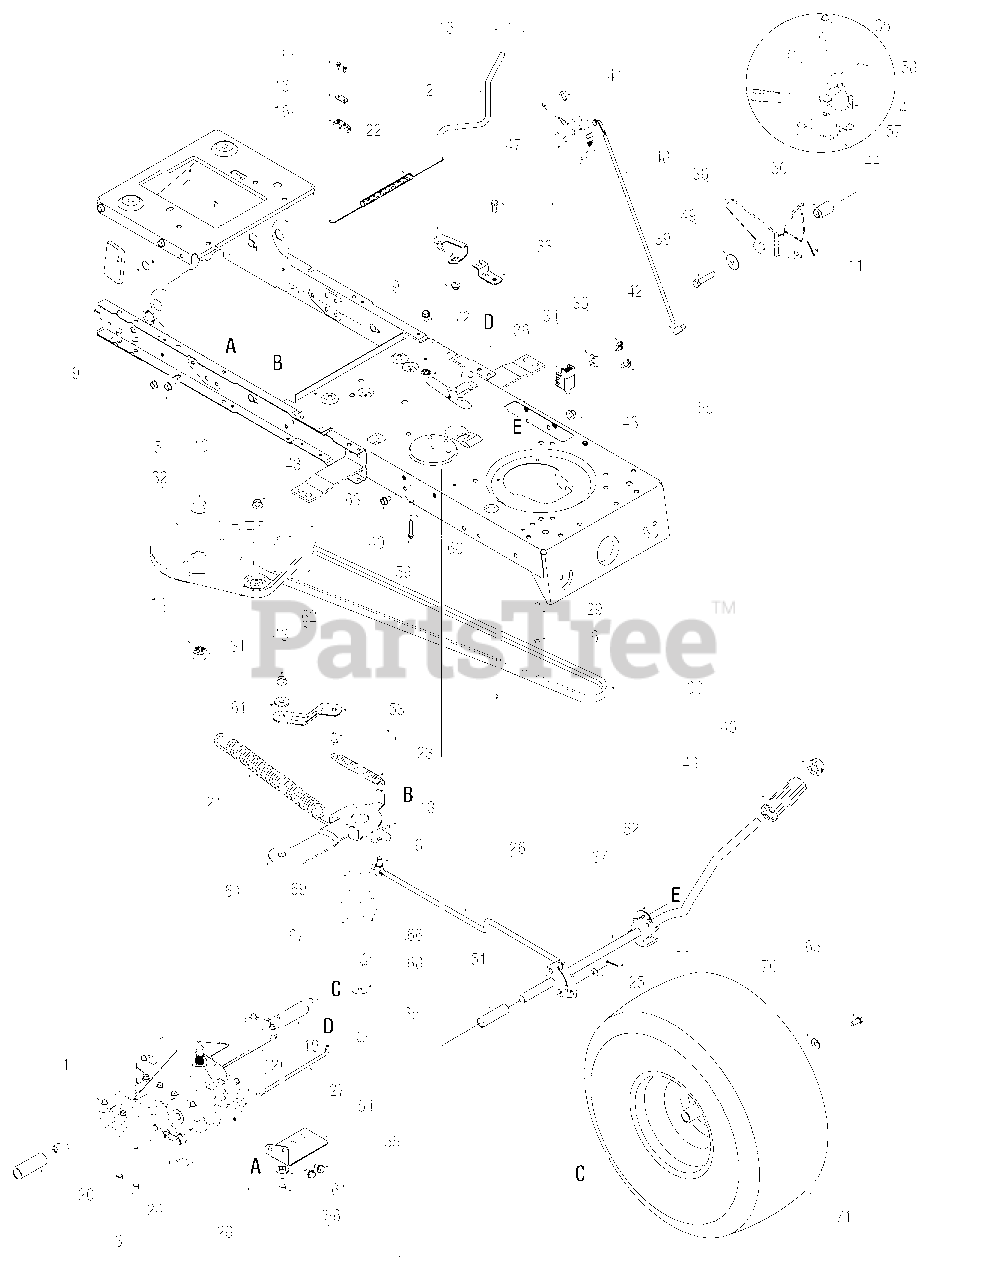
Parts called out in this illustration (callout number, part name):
1	Transmission Assembly
2	Lever Assembly, Shift
3	Screw, 5/16-18, 2.75, Gr5
4	Screw, #8-18, 0.500
5	Screw, 5/16-12, 0.750
6	Screw, 1/4-20, 1.250
7	Screw, 5/16-18, .75, Gr5
8	Ferrule, 3/8-24 x .375 Dia.
9	Nut, Flange Lock, 5/16-18, GrF
10	Nut, Flange, 9/16-18, Gr2
11	Pin, Cotter, 3/32, 1.0
12	Cotter Pin, Internal .125 Dia
13	Pin, Cotter, 1/8 x 1.25
14	Hub, Pulley, 5/8 Spline
15	Knob, Shift
16	Spring Switch, Short
17	Screw, 3/8-16 x 1.50
18	Plate, Insulator Nut
19	Sleeve, .758 x .821 x 3.3125
20	Sleeve, .758 x .821 x 2.4375
21	Spring, Extension, 1.15 OD x 7.90
22	Spring, Extension, .50 OD x 12.0
23	Spring, Extension, .80 OD x 3.28
24	Spring, Extension, .59 OD x 4.00
25	Washer, Flat, .330 x .630 x .0635
26	Contol Rod, Variable Speed
27	Rod, Shift
28	Rod, Brake
29	Spacer, .260 x .372 x 1.030
30	Belt
31	Belt
32	Pulley, V-Type, 7.25 Dia
33	Shift Bracket, Adjustable
34	Plate, Switch
35	Screw, #10-16, 0.500
36	Switch, Interlock
38	Latch Bracket
39	Screw, 3/8-16, 1.875, Gr5
40	6 Speed Shift Lever
40	7 Speed Shift Lever
41	Screw, 1/4-20, 0.500
42	Adjustment Ferrule 1/4-20
43	Nut, Flange Lock, 3/8-16, GrF
44	Control Cover
45	Push Cap, 5/8
46	Pad, Foot, 4.0
47	Shift Cont. Assembly, 6-Speed
47	Shift Cont. Assembly, 7-Speed
48	Control Rod, Speed Selector
49	Washer, Flat, .385 x 1.0 x .135
50	Spacer, Flge, .390 x .671 x 1.095
51	Spacer, .640 ID x .76 OD
52	Support Bracket, Pedal
53	Bracket, Idler
54	Torque Bracket, Transmission
55	Screw, 5/16-18, 0.625
56	Screw, 3/8-16, 1.25, Gr5
57	Shift Lever Spring
58	Control Bracket
59	Screw, 1/4-20 x 1.625
60	Spacer, .260 x .372 x 1.420
61	Spacer, Shoulder, .625 ID x .169
62	Pulley, Flat Idler
63	Pulley Ass’y, Variable Speed
64	Bracket Ass’y, Variable Speed
65	Screw, 5/16-24, .750, Gr5
66	Screw, 1/4-20, 0.625
67	Cup, Bearing
68	Washer, Flat, .330 x 1.25 x .06
69	Bearing, Ball, 17 x 40 x 12
70	Bell Washer, .34 x .872 x .060
72	Screw, 1/4-20 x .500
73	Lock Washer, 1/4
